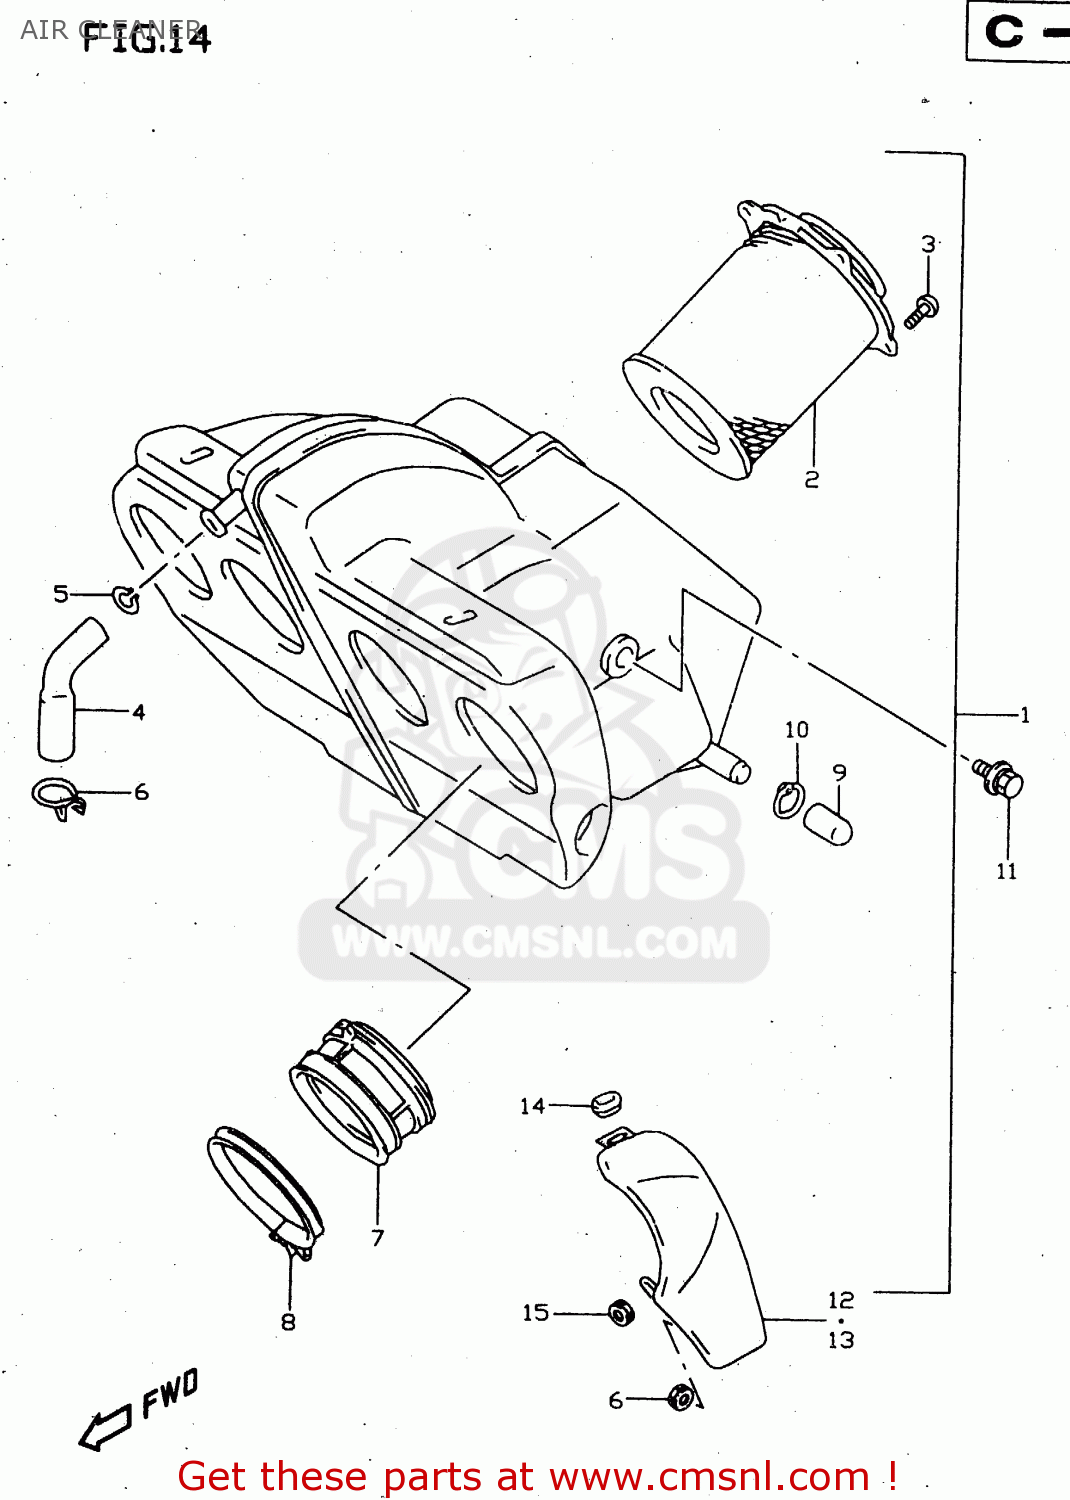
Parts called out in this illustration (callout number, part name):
1	CLEANER ASSY, AIR
2	FILTER ASSY,AIR CLEANER
3	SCREW
4	TUBE,BREATHER
5	CLIP
6	CLIP
7	TUBE,OUTLET
8	CLAMP
9	PLUG
10	CLIP
11	BOLT
12	COVER,AIR CLEANER,R
13	COVER,AIR CLEANER,L
14	GROMMET
15	CUSHION
16	CUSHION
